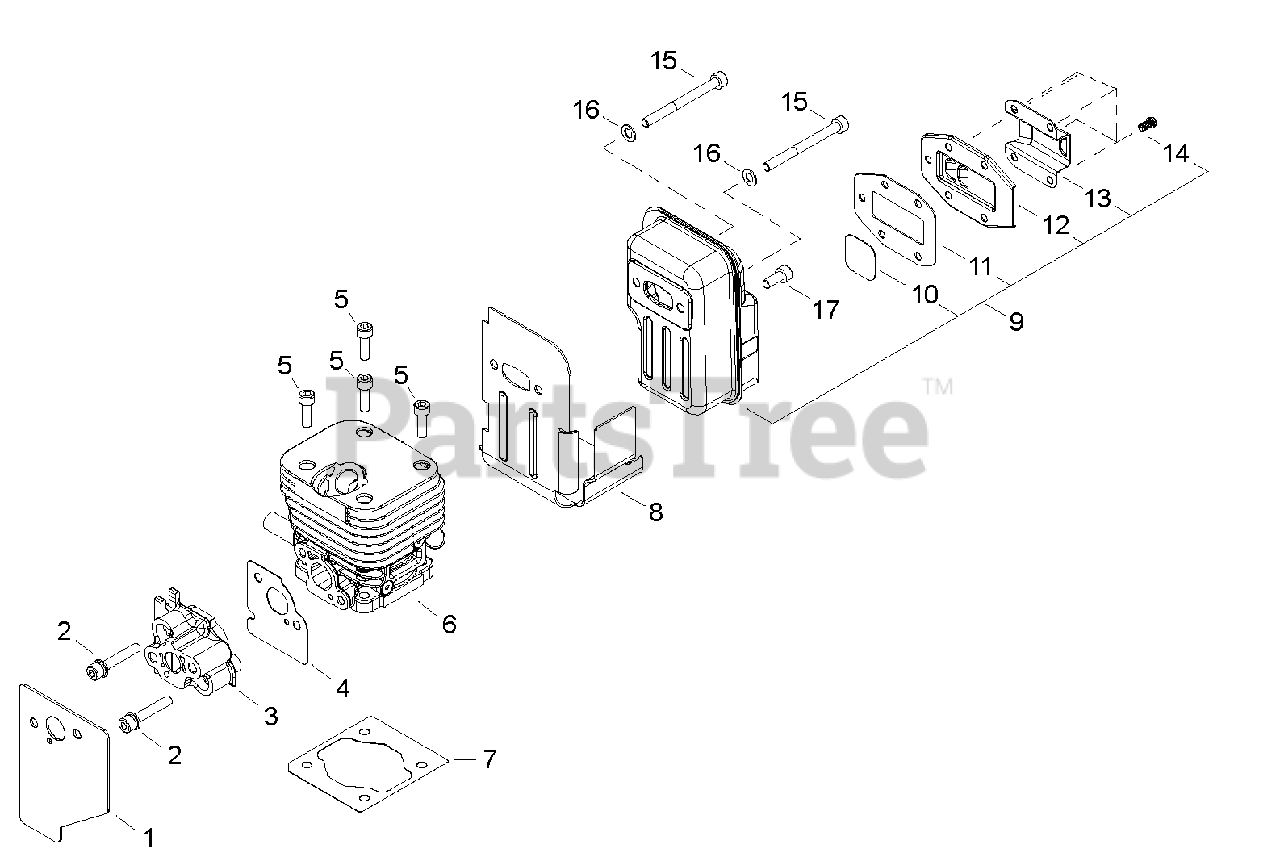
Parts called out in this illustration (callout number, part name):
1	GASKET, CARBURETOR
2	BOLT SS M5×30
3	INSULATOR
4	HEAT SHIELD, INTAKE
5	BOLT 5×16
6	CYLINDER ASSY
7	GASKET, CYLINDER
8	HEAT SHIELD, EXHAUST
9	MUFFLER ASSY
10	SCREEN, SPARK ARRESTER
11	GASKET, EXHAUST
12	COVER, SPARK ARRESTER
13	OUTLET, EXHAUST
14	SCREW M4×8
15	BOLT M5×55
16	WASHER SS 5 MM
17	BOLT 5×12
